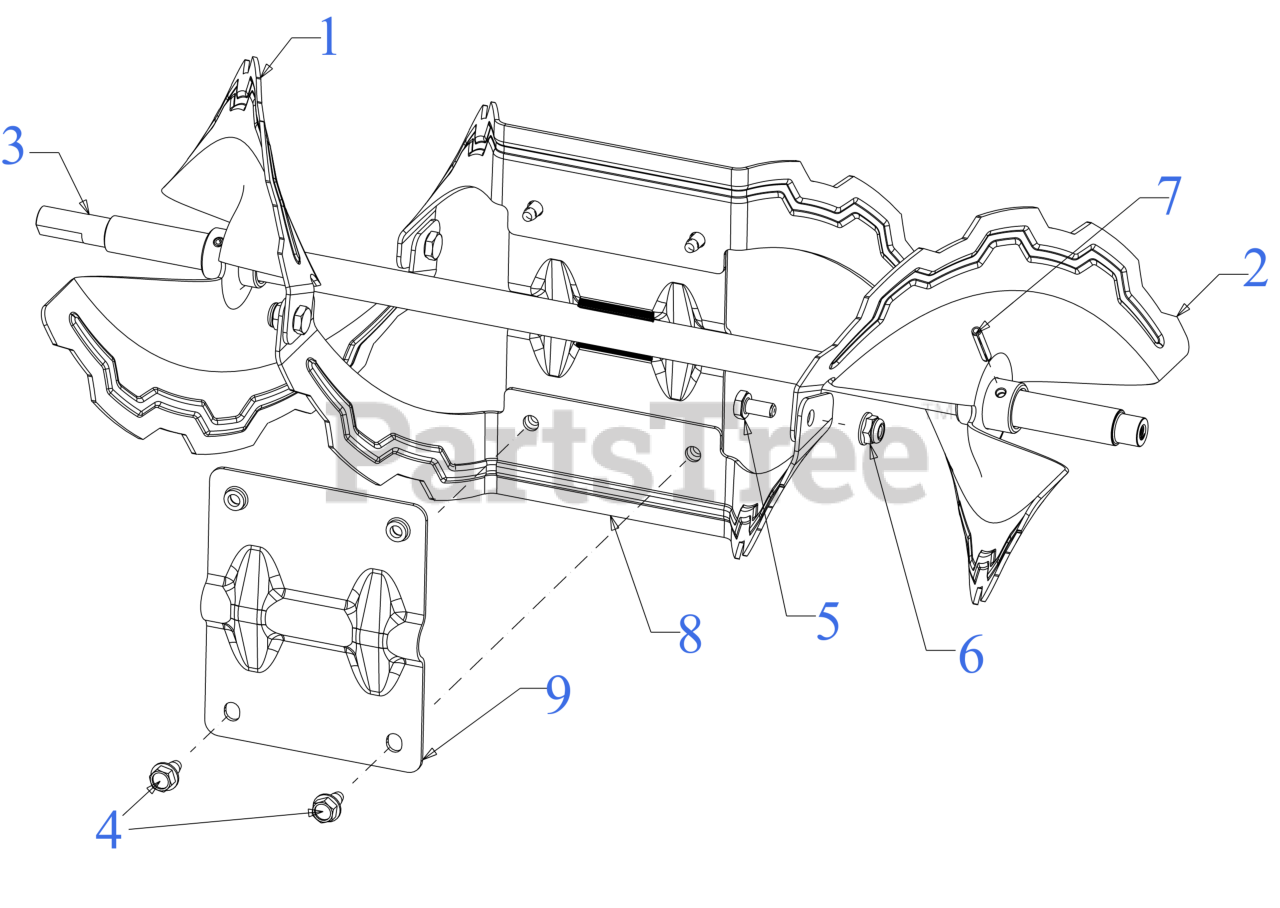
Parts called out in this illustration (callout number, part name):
1	AUGER ASSEMBLY
2	AUGER ASSEMBLY
3	AUGER ASSEMBLY
4	SCREW 1/4-20 X.500
5	SCREW 1/4-20X.5 GR5
6	FLANGE LOCK NUT
7	ROLL PIN
8	AUGER ASSEMBLY
9	AUGER ASSEMBLY
